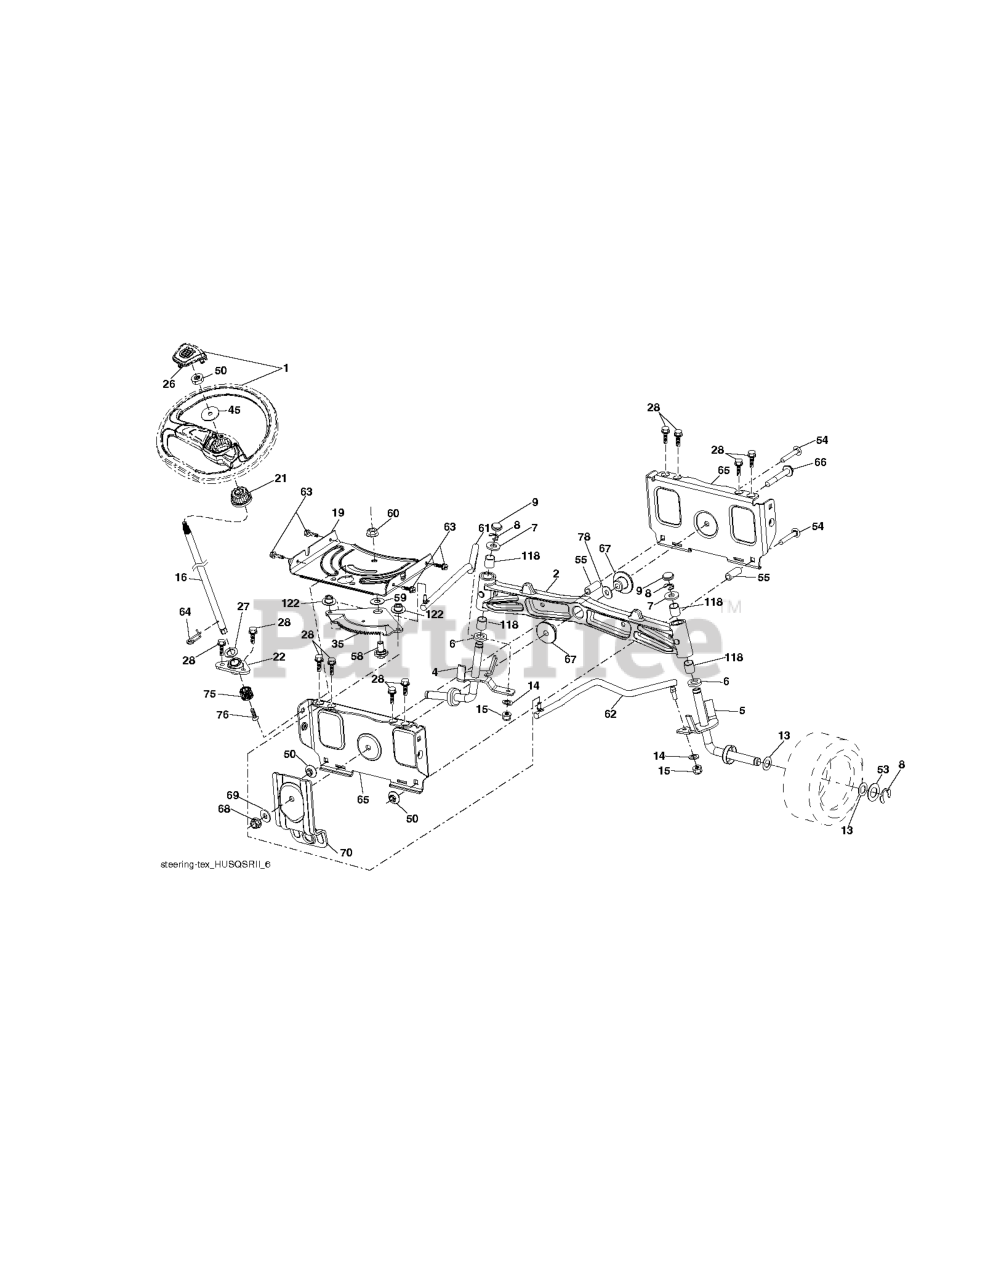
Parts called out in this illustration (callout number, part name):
1	Service Kit
2	AXLE.SVC.ASM CAST IRON.TEX
4	SPINDLE.ASM.LH
5	SPINDLE.ASM.RH
6	WASHER THRUST
9	CAP.SPINDLE.BLACK
15	NUT CROWNLOCK 3/8-24
16	SHAFT.STEER.2HIGH.SPLND.PLATED
19	PLATE.STEER.DDL.NLT/NG
21	ADAPTER.WHEEL.STEER.SPLND.ALUM
22	BEARING.SHAFT.STEER.LOWER.625
28	SCREW, 3/8-16X3/4
35	GEAR.SECTOR.PLATE.DDL.
45	WASHER.3/8ID.2-3/8OD.12GA.PLTD
50	NUT LOCK FLG 3/8-16 UNC
53	WASHER.HARDENED
55	SPACER.BRACE.AXLE
58	BOLT.SHOULDER.SECTOR.P
59	WASHER.THURST.SECTOR.S
60	NUT FLANGE LOCK 5/8-11
63	SCREW
64	RETAINER.CLIP.SPRING.S
65	BRACE.AXLE.FRONT.NLT/N
66	BOLT HEX FGHD 7/16-14 X 3 SERR
67	BUSHING.PM.FRONT AXLE
68	NUT.LOCK.FLANGE.7/16
69	WASHER.1.5X.505X.118
70	BRACKET.FRT.DECK.SUSP.RR.MT431
75	PINION.ZINC PLATED
76	SCREW HEAD SOCKET LRVB
78	THRUST WASHER
118	BUSHING, AXLE CAST
122	CAP.GEAR.SECTOR.TEX
